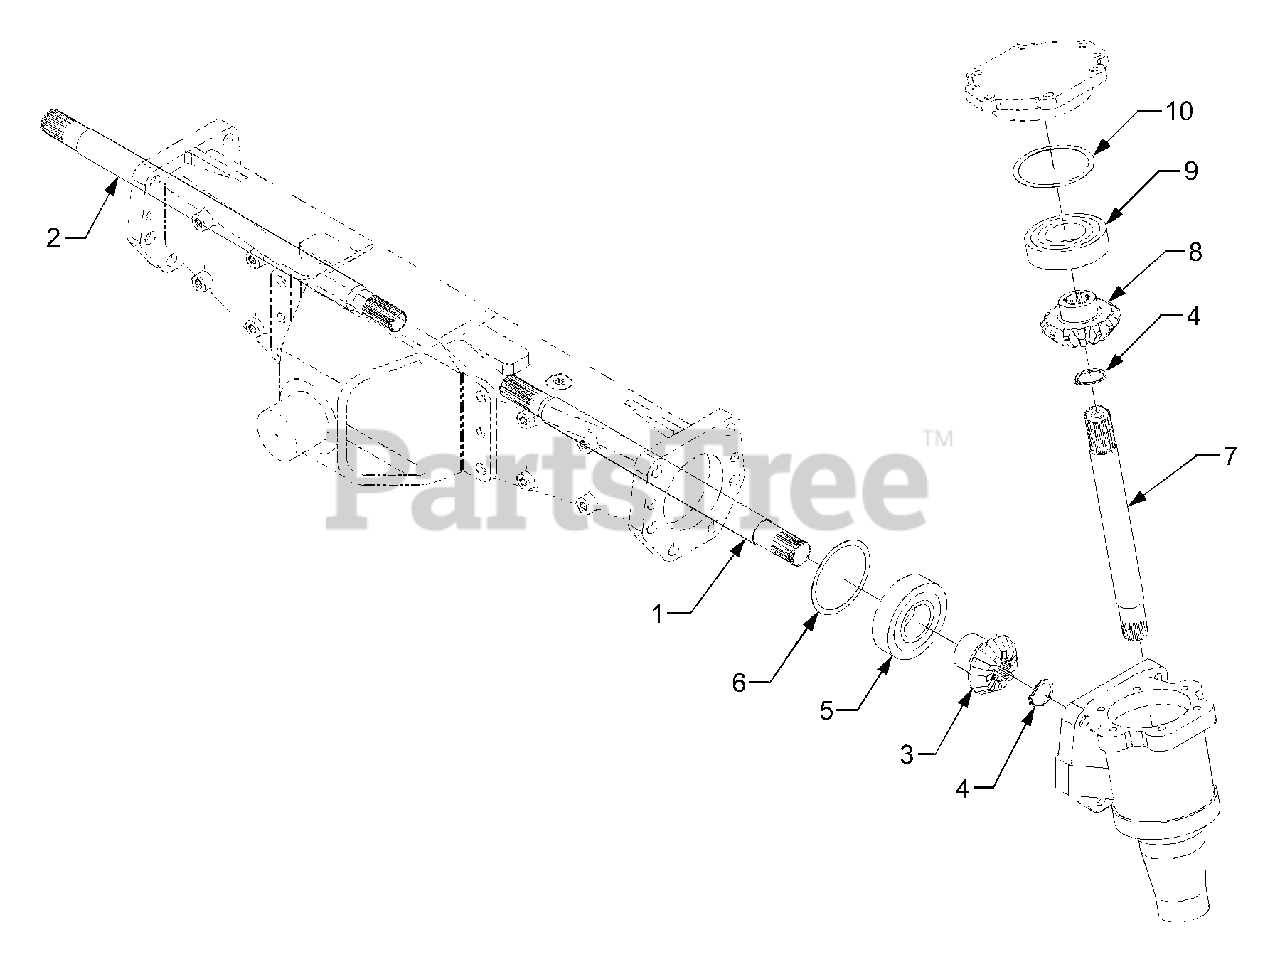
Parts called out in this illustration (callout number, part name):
1	Shaft, Defferential Gear(LH)
2	Shaft, Defferential Gear(RH)
3	Gear 12, Bevel
5	Bearing, Ball
7	Shaft, Bevel Gear
8	Gear 16, Bevel
9	Bearing, Ball
